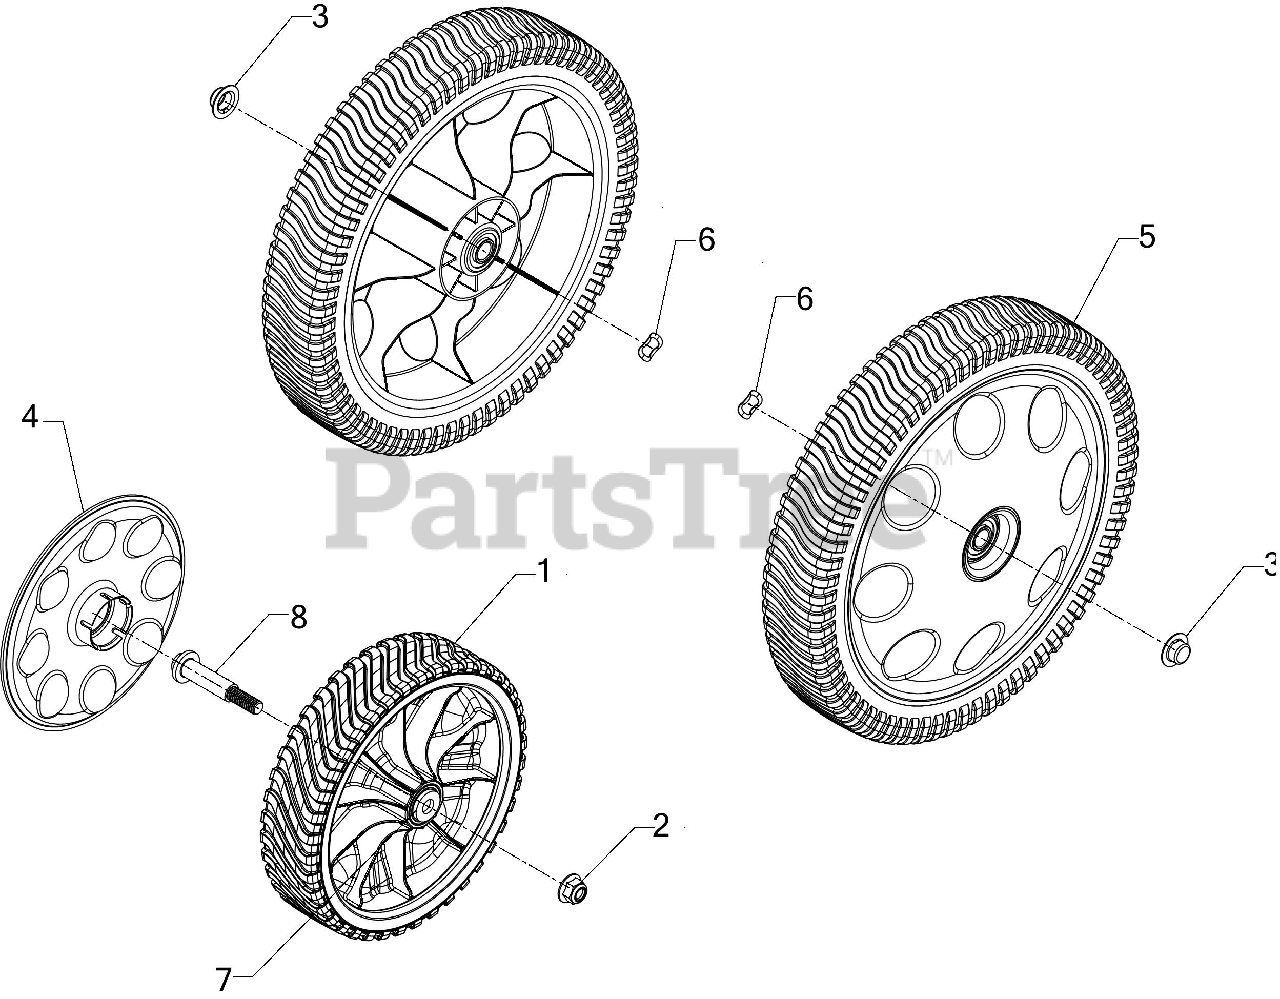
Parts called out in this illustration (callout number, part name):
1	WHEEL ASSEMBLY (8 x 2)
5	REAR WHEEL12X2.1
6	WAVE WASHER
7	FLAT WASHER
8	SHOULDER SCREW .496X1.605 3/8-16
